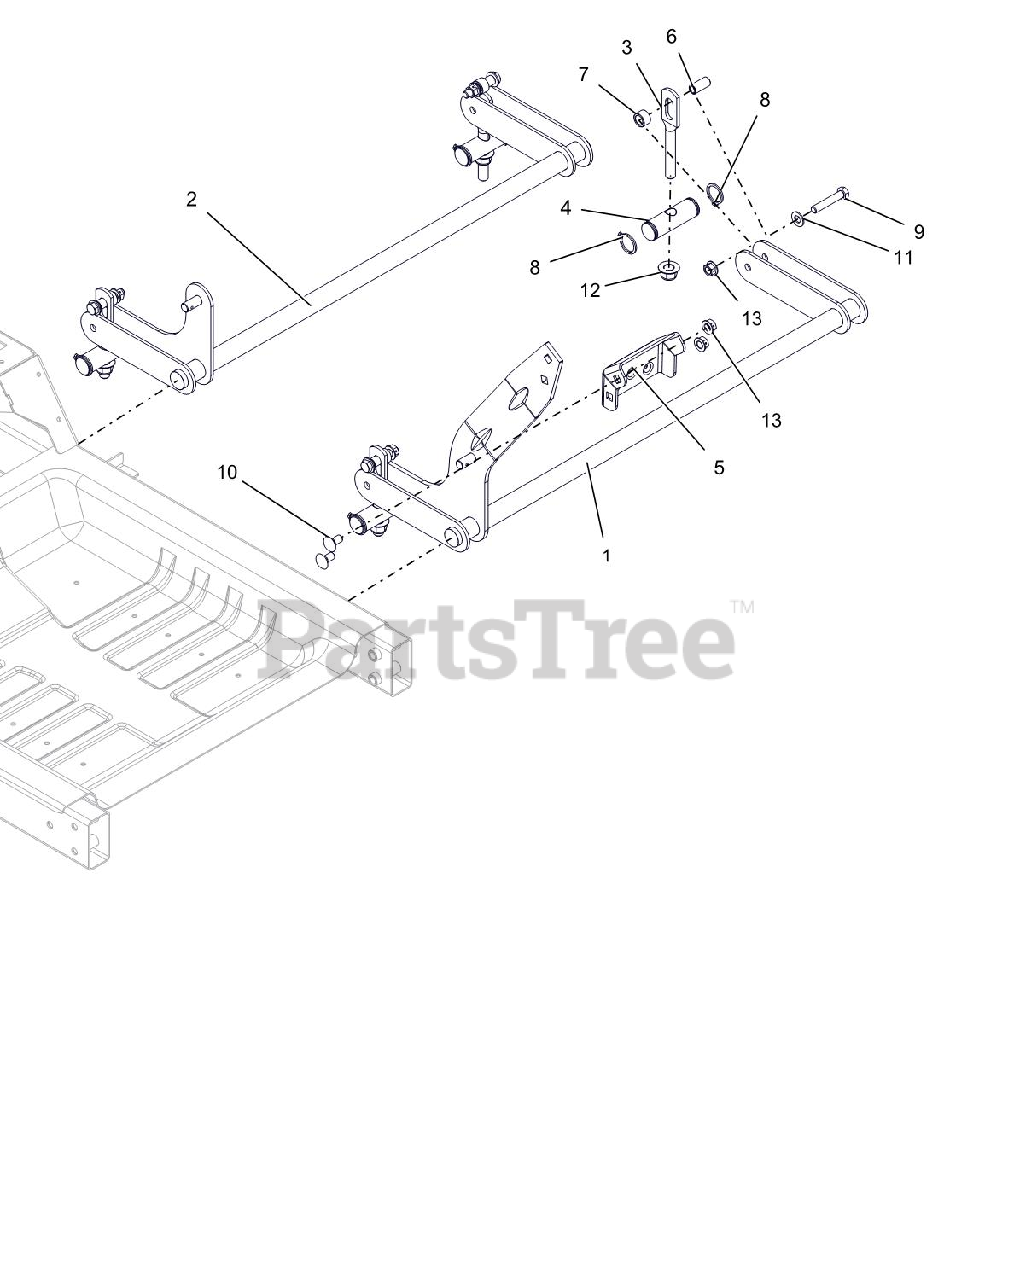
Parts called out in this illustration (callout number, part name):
1	WLDMT, FRONT DECK LIFT PIVOT
2	WLDMT, REAR DECK PIVOT
3	LINK, DECK
4	SHAFT, DECK LINK PIVOT
5	PEDAL, DECK LIFT (BOLT ON)
6	BSHG-SLV .385X.500X1.045
7	BSHG-SLV .510X.751X.475
8	RG-RTNG-EXT 1.00X.078
9	BLT-HEX .38-16X2.00 GR8 YWZC
10	BLT,RHSN .38-16X.75 G5 BFP
11	@WSHR-FL-STL.406X.812X.065 YWZ
12	@NUT-LK-NYL-FLG .50-13 YWZC
13	NUT-LK-CTR-FLG .38-16 YWZC
